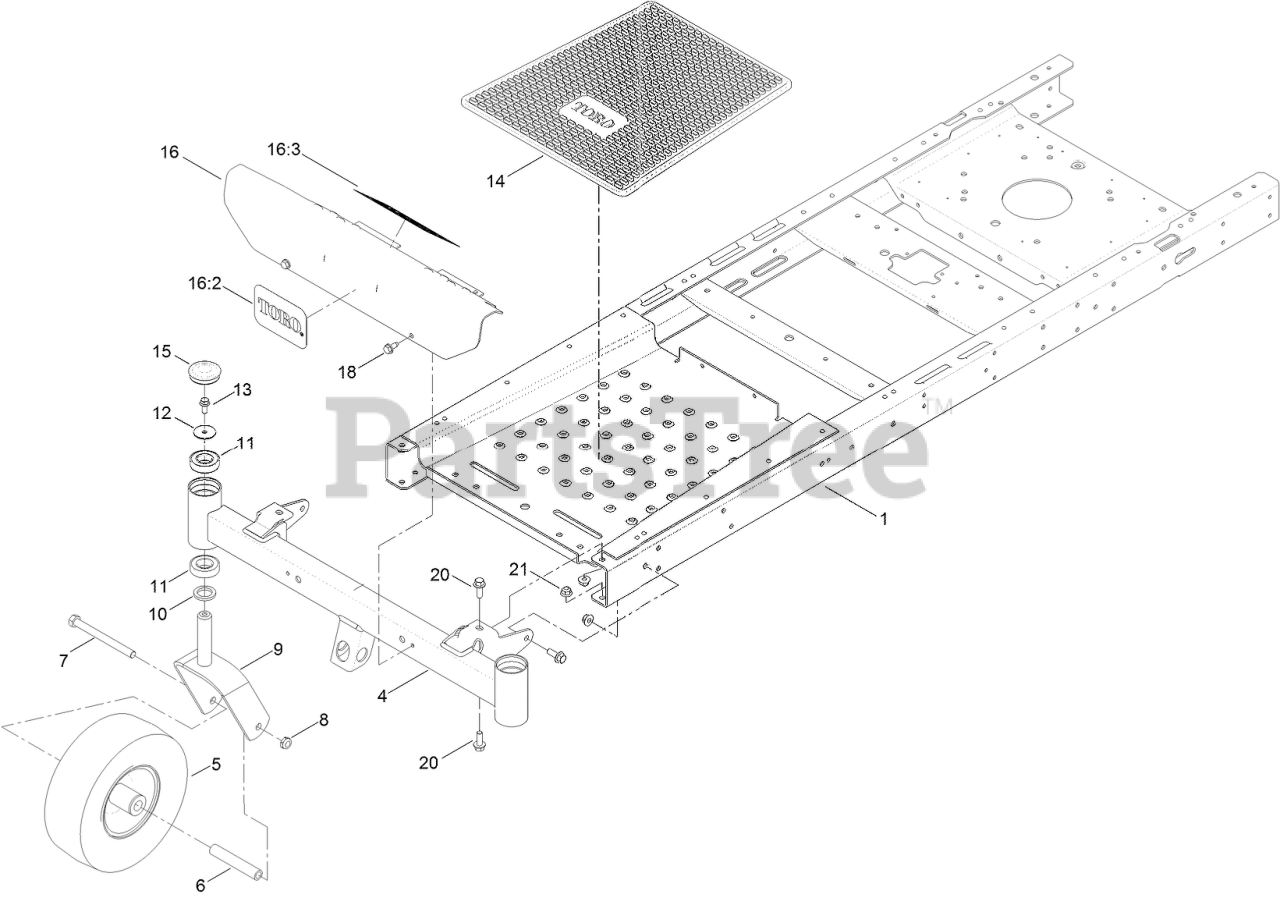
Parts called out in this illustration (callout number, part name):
1	FRAME ASM
4	AXLE-FRONT, NARROW
5	Caster Wheel ASM
6	BUSHING-SPANNER
7	SCREW-HH
8	NUT-LOCK, NI
9	CASTER FORK ASM
10	WASHER-THRUST
11	BEARING-BALL
12	WASHER-FLAT
13	SCREW-HHF
14	MAT-FLOOR
15	CAP-GREASE
16	FOOTREST ASM
16:3	DECAL-DANGER
18	SCREW-HWHTF
20	SCREW-HHF
21	NUT-HF, NI
